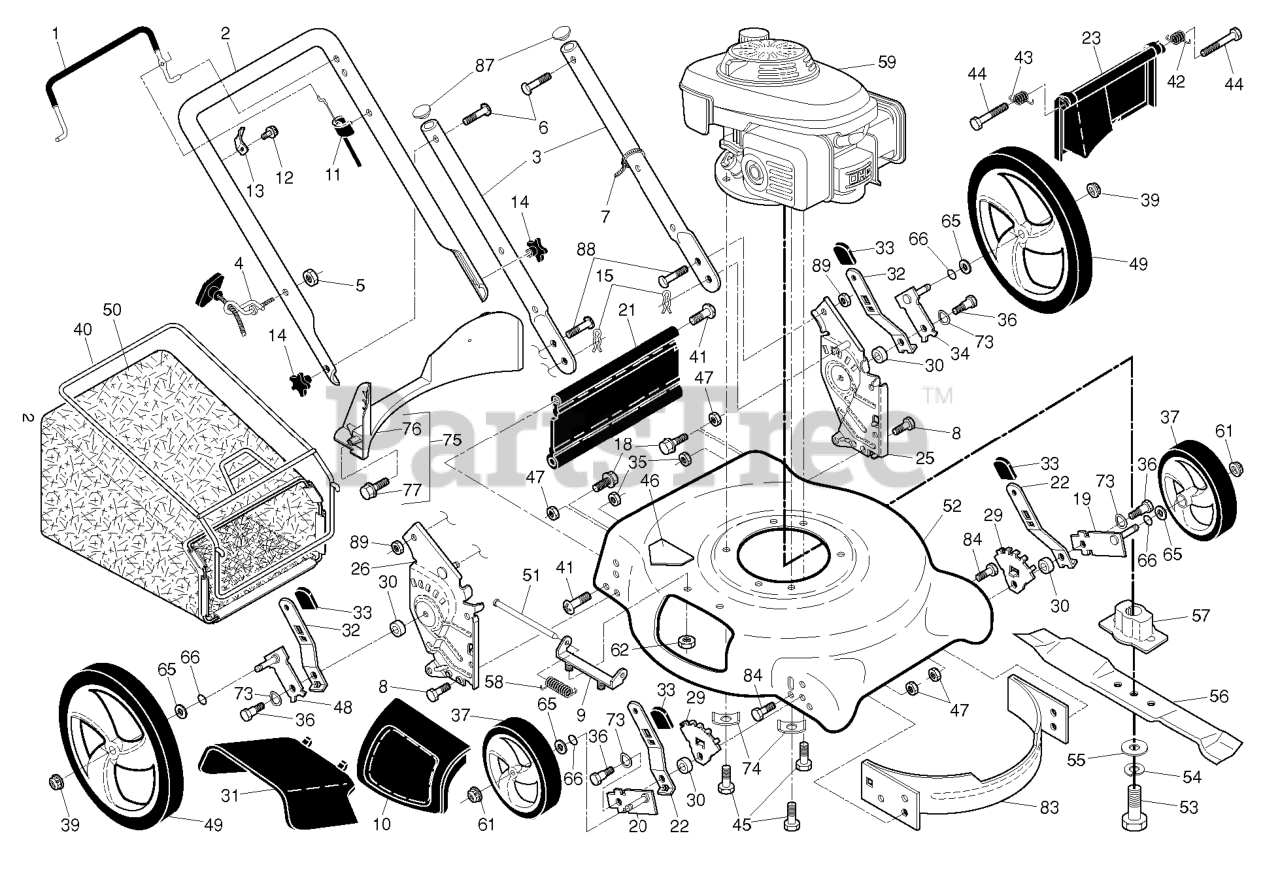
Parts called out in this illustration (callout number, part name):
1	RP BAIL.OVER.MOLD.STRAIGHT.ORG
2	HANDLE.UP.DST.SS/VS.FG/RGD.CRE
3	HANDLE.LOWER.DOME.BT.GREY
4	GUIDE.ROPE.BLK.ZINC.CHROM
5	T-KNOB.NEW ROPE GUIDE
6	BOLT, HANDLE 5/16-18X1.75
7	TIE GUIDE
8	BOLT.FIN.HEX.5/16-18X3/4
9	BRACKET.ASM.HOUSING.EZ.MUL
10	DOOR.MULCH.21".REAR.PUSH.GRAY
11	CONTROL.ZONE.ASM
13	BRACKET.UPSTOP.RT
14	KNOB.HANDLE.PLASTIC.STAR.BLACK
15	HAIRPIN COTTER
18	SCREW 1/4X20
19	AXLE ARM ASSY FRONT LH
20	AXLE ARM ASSY FRONT RH
21	RP_KIT.SKIRT.21 DOMED.W/LIP
22	SELECTOR SPRING, FRONT
23	DOOR.REAR.21.DOMED.498
25	BRACKET.ASM.HAND.HW.21.LT.GREY
26	BRACKET.ASM.HAND.HW.21.RT.498
29	WHEEL ADJ BRACKET FRONT
30	SPACER.HEIGHT.ADJUSTER
31	DEFLECTOR.CLIPPING.21.GREY
32	SPRING.SEL.22.ECON.HI-WHL.RATO
33	SELECTOR KNOB
34	AXLE ARM ASSY REAR LH
35	NUT.FLANGE.HEX.5/16X18.BLACK
36	SHOULDER BOLT 5/16-18
37	WHEEL AND TIRE ASSY, REAR
39	NUT.HEX.FLANGE.3/8-16.LOCKNUT
40	FRAME.BAG.21.REAR.DOMED.PUSH
41	SCREW.1/4-20X21/4.HEX.
42	SPRING.LH.22.REAR.DOOR.EZ.EMPT
43	SPRING.RH.22.REAR.DOOR.EZ.
45	BOLT 3/8-16X1-1/8
46	DANGER DECAL
47	NUT.LOCK.5/16-18
48	AXLE ARM ASSY REAR RH
49	WHEEL.12 X 1.75 CFH3SPK.RAD3
50	GBAG.23230247.SILVER.HUSQ.BLUE
51	ROD.HINGE.COMBI-C
52	HOUSING.21.M/C.DOME.ORANGE
53	SCREW, HEX HD 3/8-24 X 1-3/8
54	LOCKWASHER
55	WASHER,HARDEN
56	BLADE.21.PUSH/RWGD/FWGD
57	ADAPTOR.BLADE.7/8
58	TORSION SPRING
61	NUT.HEX.FLANGE.3/8-16.LO(3 2)
62	LOCKNUT.NYLOC.1/4-20
65	WASHER.FLAT.1/2
66	O-RING..070X.487.NEOPRENE
73	WASHER.CURVED.CYLINDRICAL
74	WASHER.ENGINE.BZP
75	KIT.BAFFLE.REAR.PLASTIC.21.RD
76	BAFFLE.REAR.PLASTIC.21.RD.ECON
77	SCREW.HX.13X.750
83	BAFFLE.FRONT.21.DOME.US
84	BOLT.5/16HEX.WHS.HD
87	PLUG.PLASTIC.7/8".14-20.GAUGE
88	BOLT
89	LOCKNUT-FLANGE 5/16-18
